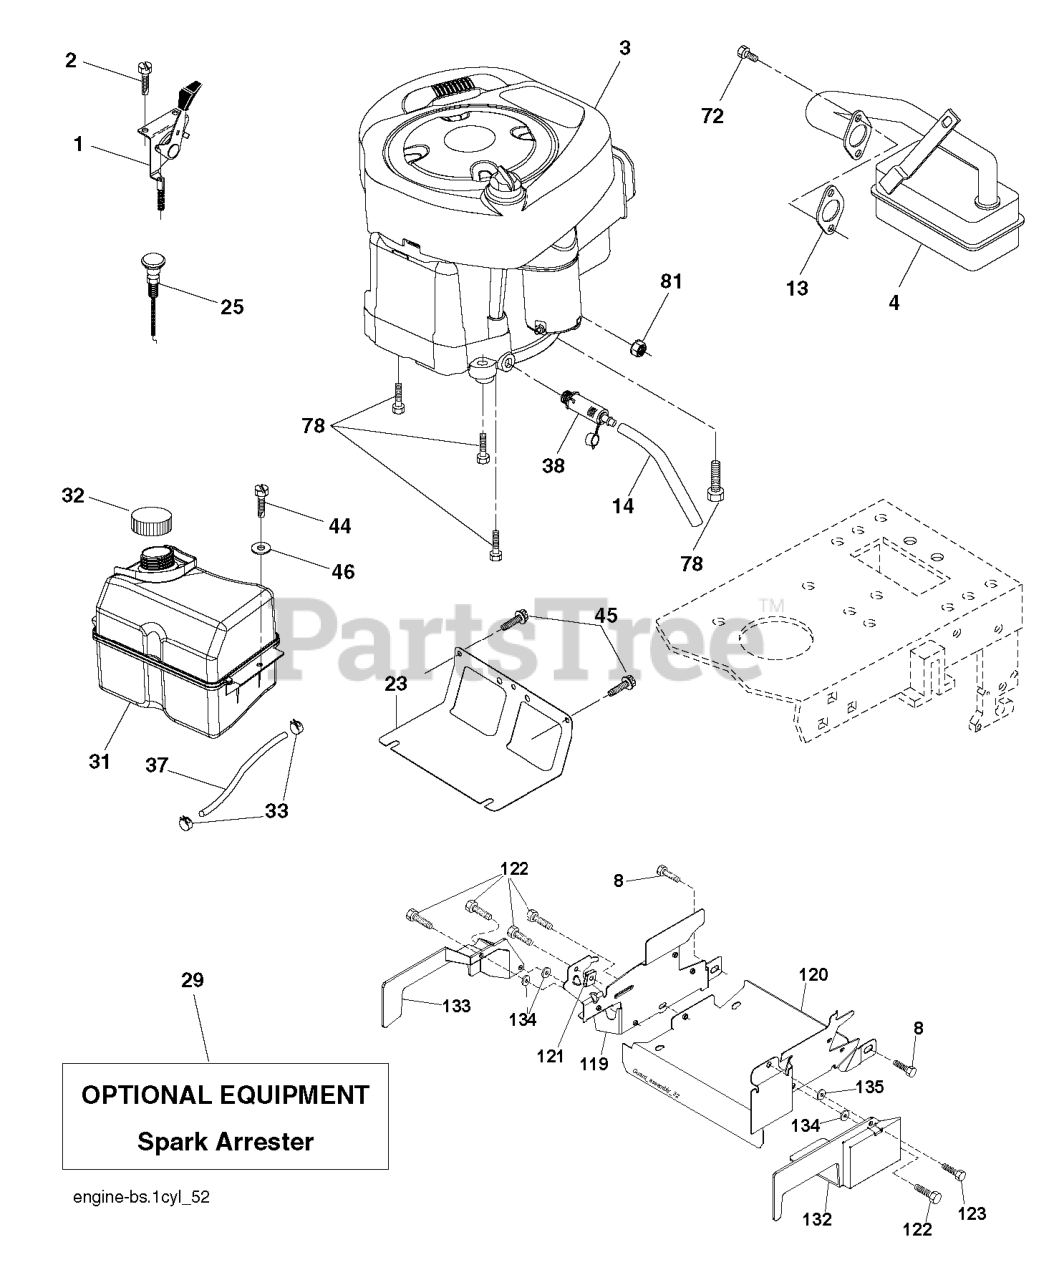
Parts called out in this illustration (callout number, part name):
1	CONTROL.THROTTLE/CHOKE.BLACK
2	SCREW
4	MUFFLER.B&S.MODEL.21.11HP.OHV
8	BOLT.5/16-18UNCX3/4 W/SEMS.BLK
13	REPL BY 532 27 22-93
14	TUBE, DRAIN OIL ASM.
23	SHIELD.BROWNING.DBR.GUARD
25	KNOB.ERGO.EXTENDED.RED (1 2)
29	KIT.SPARK ARRESTOR 794945 B&S
31	TANK.FUEL.FRT.N/CAP.2.0GAL.DAP
32	FUEL CAP
33	HOSE CLAMP
37	LINE.FUEL.20
38	PLUG DRAIN OIL EASY
44	SCREW HEXWSHR 1/4-20X3/4
45	SCREW, 3/8-16X3/4
72	SCREW.SOCKET HD.5/16-1
78	SCREW.3/8-16
81	NUT
119	LENKRAD
120	GUARD 532199767
122	SCREW.1/4-20X5/8
123	SCREW, 5/16-18 X 1/2
132	SHIELD RIGHT
133	SHIELD LEFT
134	PALNUT 1/4
135	WASHER 5/16"
